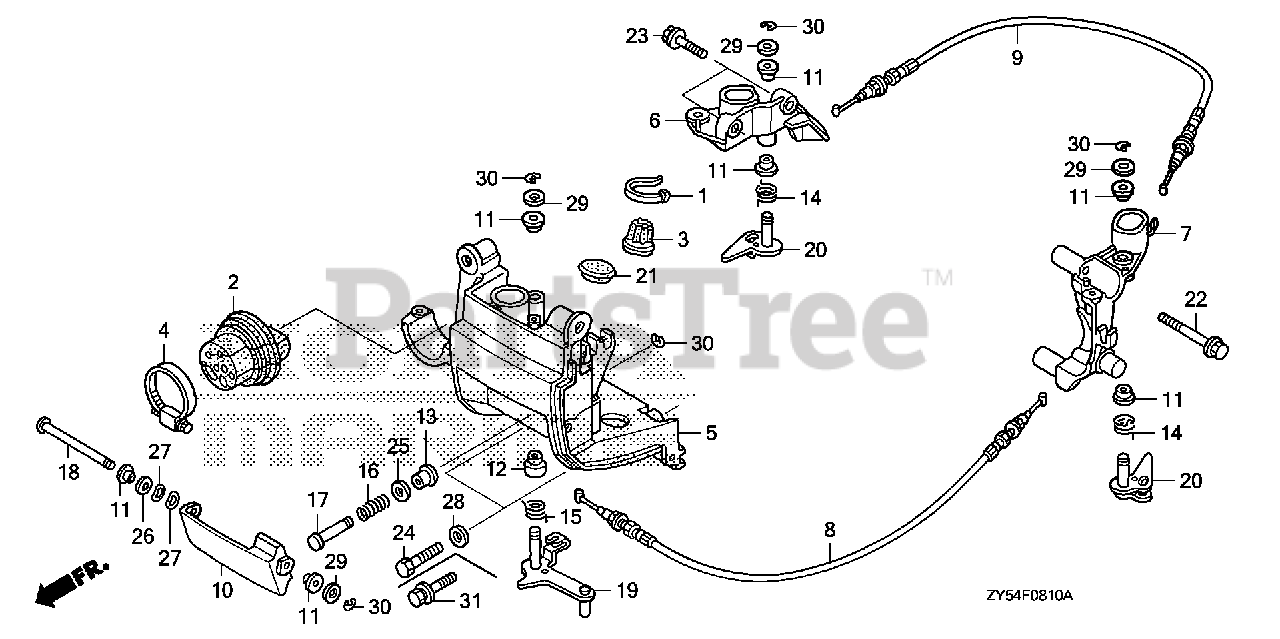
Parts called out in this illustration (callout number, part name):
1	BAND (BLACK 3.5X140)
2	GROMMET, REMOTE CONTROL CABLE
3	GROMMET, CASE (LOWER) (C)
4	BAND, CASE GROMMET (LOWER)
5	BRACKET, FR. COVER (LOWER) *NH282MU* (OYSTER SILVER METALLIC-U)
6	BRACKET, R. SIDE COVER
7	BRACKET, L. SIDE COVER
8	CABLE A, COVER LOCK
9	CABLE B, COVER LOCK
10	LEVER, COVER LOCK *NH282MU* (OYSTER SILVER METALLIC-U)
11	BUSH A, COVER LOCK
12	BUSH A, COVER LOCK
13	BUSH B, COVER LOCK
14	SPRING, COVER LOCK HOOK
15	SPRING, COVER LOCK HOOK
16	SPRING, LOCK LEVER RETURN
17	SHAFT, COVER OPEN
18	SHAFT, FR. LOCK
19	LOCK, FR.
20	LOCK, SIDE
21	CAP, L. SIDE COVER
22	BOLT, FLANGE (8X55)
23	BOLT, FLANGE (6X22)
24	BOLT, HEX. (8X30)
25	WASHER, PLAIN (8MM)
26	WASHER, PLAIN (10MM)
27	WASHER, WAVE (10MM)
28	WASHER, PLAIN (8MM)
29	WASHER, PLAIN (8MM)
30	E-RING (6MM)
